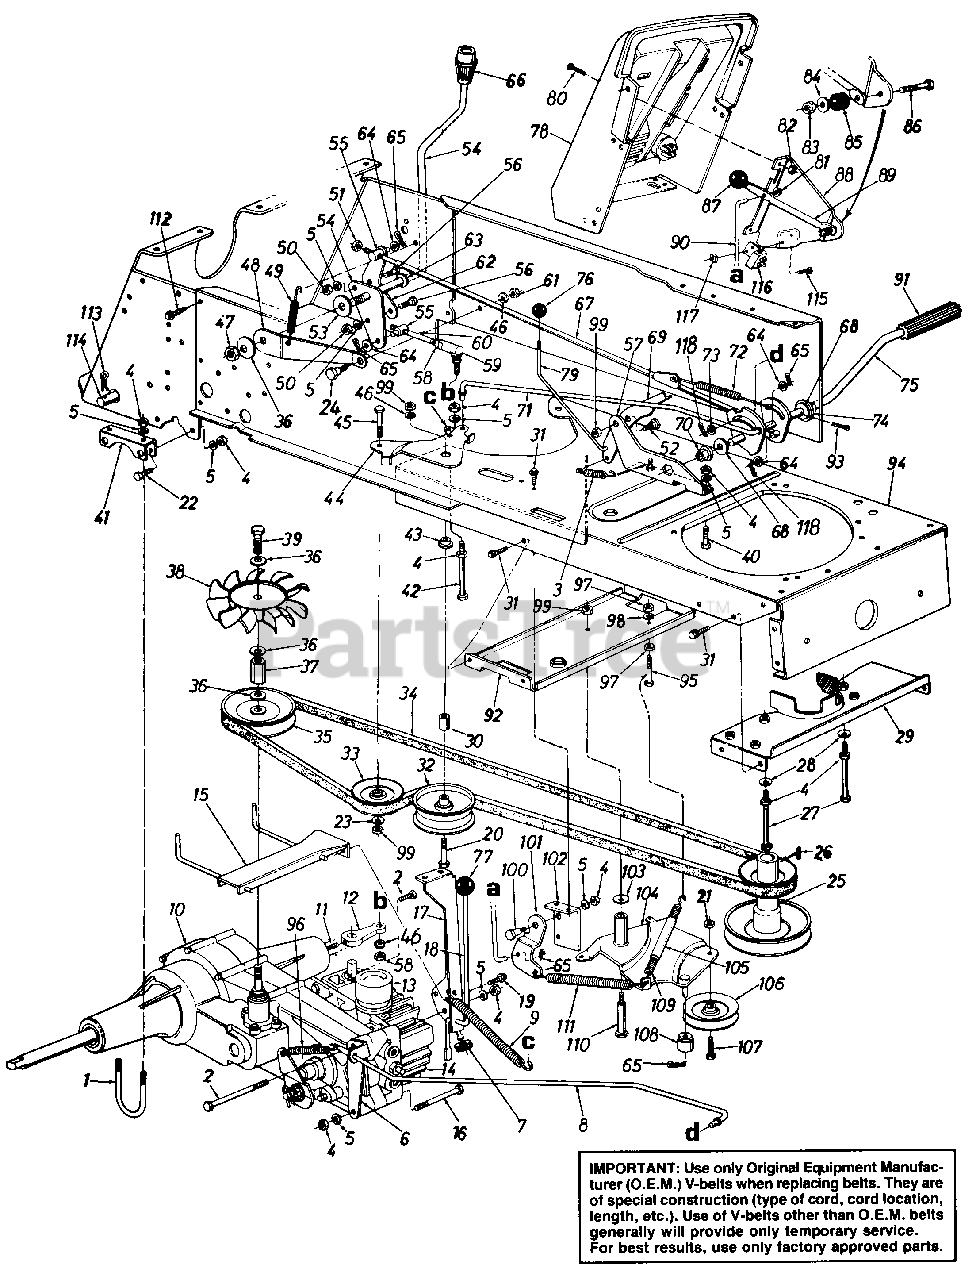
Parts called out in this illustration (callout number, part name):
1	U-Bolt 5/16-18 x 3.25" Lg.
2	Hex Patch Bolt 5/16-18 x 4.5" Lg. (Gr. 5)
3	Ext. Spring .5" O.D. x 1.55"
4	Hex Nut 5/16-18 Thd.
5	L-Wash. 5/16" I.D.
6	Brake Rod Guide Brkt.
7	Rubber Wash. .33" I.D. x .87"
9	Ext. Spring .62" O.D. x 6.12" Lg.
11	Set Screw 5/16-24 x .38" Lg.
12	Pintle Shift Lever
13	Reservoir
14	Hydrostatic Pump
15	Belt Guard Ass'y.
16	Hex Bolt 5/16-18 x 4.5' Lg. Gr. 5
17	Transaxle Torque Bracket
18	Transaxle Control Rod
19	Hex Wash. Hd. B-Tap Scr. 5/1 6-18
20	Hex Bolt 3/8-16 x 2.75" Lg.
21	Hex Cent. Lock Nut 3/8-16 Thd.
22	Hex Bolt 5/16-18 x .75" Lg. Gr. 5
23	Fl-Wash. .385" l.D. x .87" O.D.
24	Shld. Bolt .5" Dia. x .212"
25	Engine Pulley
26	Sq. Key 1/4 X 1.5" Lg.
27	Hex Bolt 5/16-18 x 5.25" Lg.
28	Bell-Wash. .345" I.D. x .88" O.D.
29	Belt Keeper Brkt. Ass'y.
30	Spacer .375" I.D. x .75" Lg.
31	Hex Wash. Hd. TT-Tap Scr. 1/4-20 x .5" Lg.
32	Fl-ldler Pulley 3.25" Dia.
33	V-Belt Idler
34	V-Belt
35	Transmission Pulley 4.25" O.D.
36	Bell-Wash. .56" I.D. x 1.5n
37	Fan Adapter Nut 9/16-18 Thd.
39	Hex Bolt 9/16-18 x .5" Lg.
40	Hex Bolt 5/16-18 x .75" Lg.
41	Transaxle Mtg. Bracket
42	Hex Bolt 5/16-18 x 2.75" Lg.
43	Shld. Spacer .625" l.D.
44	Clutch Idler Bracket
45	Hex Bolt 3/8-16 x 1.5" Lg.
46	L-Wash. 3/8" I.D.
47	Hex Jam Nut '/2-20 Thd.
48	Speed Control Rod Torque Brkt.
49	Ext. Spring 2.5" Lg.
50	Hex Nut 5/16-24 Thd.
51	Hex Jam Nut 3/8-24 Thd.
52	Shld. Bolt .50" Dia. x .170n
53	Fiber Washer .54" I.D. x 1.75"
54	Speed Control Handle Ass'y.
55	Ferrule 3/8-24 Thd.
56	Hex Bolt 5/16-24 x .62" Lg.
57	Foot Pedal Mtg. Brkt.
58	Hex Nut 3/8-24 Thd.
59	Ball Joint Ass'y.
60	Control Rod 3/8-24 x 3.75" Lg.
61	Hex Nut 3/8-16 Thd.
62	Speed Selector Handle Brkt.
63	Fl-Wash. .531" l.D. x 1.25" O.D.
64	Fl-Wash. .385" l.D. x .62" O.D.
65	Internal Cotter Pin
67	Neutral Return Rod
68	Fl-Wash. .64" l.D. x 1.24" O.D.
69	Parking Brake Lock Brkt.
70	Hex Flange Brg. .634" Dia.
71	Clutch Idler Rod
72	Extension Spring 8 Lg.
73	Fl-Wash. .344" l.D. x .62" O.D.
74	Flange Bearing w/Flats
75	Foot Pedal Ass'y.
76	Ball Knob Brake
77	Ball Knob 1/4-20 Thd.
78	Dash Panel Ass'y.
79	Parking Brake Link.
80	Truss Mach. Scr. 1/4-20 x .5" Lg.
81	Push Nut 1/4" O.D. Rod
82	Hex Sems Nut 1/4-20 Thd.
83	Hex L-Nut 1/4-20 Thd.
84	Fl-Wash. .281" l.D. x .73" O.D.
85	Rubber Wash. .33" l.D. x .87"
86	Hex Bolt 1/4-20 x 1.25" Lg.
87	Knob-Blade Clutch
88	Deck Clutch Cont. Brkt.
89	Blade Clutch Lever
90	Deck Control Rod
91	Foot Pad
92	Deck Idler Support Brkt.
93	Cotter Pin 1/8" Dia.
94	Lower Frame
95	Hex Bolt 1/4-20 x 2" Lg.
96	Ext. Spring 3.675" Lg.
97	Hex Nut t/4-20 Thd.
98	L-Wash. 1/4" l.D.
99	Hex Cent. L-Nut 3/8-16 Thd.
100	Shld. Bolt .437" Dia. x .162"
101	Deck Control Pivot Brkt.
102	Parking Brake Mtg. Brkt.
103	Bell-Wash. .380" l.D. x .88" O.D.
104	Idler Brkt. Deck Ass'y.
105	Convoluted Conduit 4" Lg.
106	V-Belt Idler
107	Hex Bolt 3/8-24 x 1.5" Lg.
108	Spacer
109	Ext. Spring 6.37" Lg.
110	.Shld. Bolt .498" Dia. x 2.05n
111	Ext. Spring 6.12" Lg.
112	Hex Wash. AB-Tap Scr. 5/16-x 75" Lg
113	Hitch Pin Clip
115	Truss Mach. Scr. #10-24 x
116	Satety Switch
117	Hex Nut #10-24 Thd.
118	Cotter Pin 3/32" Dia. x 1.0" Lg.
